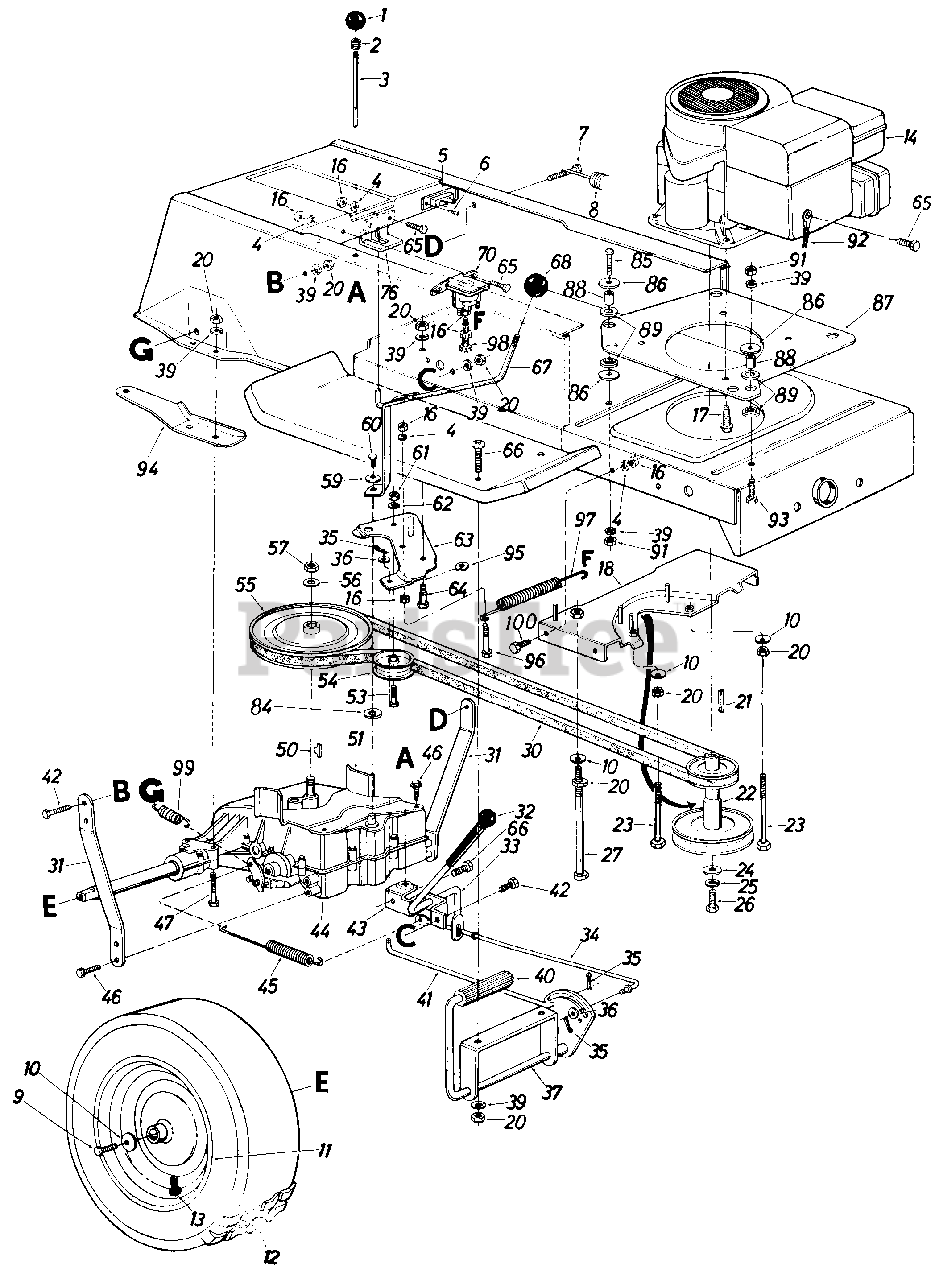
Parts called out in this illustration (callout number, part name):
1	Ball Knob 1.25" O.D. x 1/4-20 Thd.
2	Compression Spring .30" O.D. x 1.00" Lg.
3	Brake Lockout Rod
4	L-Wash. 1/4" I.D.
5	Circuit Breaker
6	Truss Hd. Phil. Scr. #10 x 1/2" Lg.
7	Hex Bolt 5/16-18 x 1.25" Lg.
8	Ext. Spring .99" O.D. x 11.00" Lg.
9	Hex Bolt 5/16-24 x .75" Lg.
10	Bell-Wash. 5/16" I.D.
11	Rear Wheel Rim Only
16	Hex Nut 1/4-20 Thd.
17	Hex Bolt 3/8-16 x 1.25" Lg.
18	Belt Guard Brk't. Ass'y.
20	Hex Nut 5/16-18 Thd.
21	Sq. Key 1/4" x 1/4" x 2.00" Lg.
22	Two Step Engine Pu I ley
23	Hex Bolt 5/16-18 x 5.25" Lg.
24	Fl-Wash. 7/16" I.D. x 1.25" O.D. x .180
25	L-Wash. 7/16" I.D.
26	Hex Bolt 7/16-20 x 1.50" Lg.
27	Hex Bolt 5/16-18 x 5.25" Lg.*
30	"V "-Belt "A" G lass 85" Lg. Bare Back
31	Transaxle Brace
32	Grip
33	Hill Holder Brake Handle
34	Brake Rod
35	Cotter Pin 3132" Dia. x 1 .00"
36	Fl-Wash. .344" I.D. x .625" O.D.
37	Brake and Clutch Pedal Ass'y.
39	L-Wash. 5/16" I.D.
40	Foot Pedal Pad
41	Clutch Rod
42	Hex Bolt 5/16-18 x .75" Lg.
43	Brake Lock and Handle Support Brk't.
44	Transaxle Complete
45	Ext. Spring .590" O.D. x 7.08" Lg.
46	Hex Wash. Hd. AB-Tap Scr. 5/16 x .62" Lg.
47	Hex Bolt 5/16-18 x 2.50" Lg.
50	#4 Hi-Pro Key 3/32 x 5/8" Dia.
51	Transaxle Belt Keeper
53	Hex Bolt 3/8-16 x 1.50" Lg.*
54	Flat Idler Pulley 3/8 I.D. x 2.75 O.D.
55	Transaxle Pulley
56	L-Wash. 1/2" I.D.
57	Hex Nut 1/2-20 Thd.*
59	Bell-Wash. .26" I.D. x .75" O.D.
60	Hex Bolt 1/4-28 x .62" Lg.
61	Hex Nut 3/8-16 Thd.
62	L-Wash. 3/8" I.D.
63	Idler Brk't. Ass'y
64	Shld. Scr. .437" Dia. x 1.80" Lg. (5/16-18)
65	Hex Bolt 1/4-20 x .62" Lg.
66	Truss Hd. Mach. 5/16-18 x .75" Lg.
67	Shift Lever Ass'y
68	Ball Knob 1.25" O.D. x 3/8 16 Thd.
70	Solenoid
76	Shift Lever Pivot Brk't.
84	Special Wash. 1.00" O.D.
85	Hex Bolt 5/16-24 x 1.25" Lg.
86	Fl-Wash. 1.25" O.D. x .320" I.D.
87	Engine Mounting Plate
88	Spacer
89	Engine Mounting Grommet
91	Hex Nut 5/16-24 Thd.
92	Electric Ground Wire
93	Hex Bolt 5/16-24 x 1.50" Lg.*
94	Transaxle Support Brk't. R.H.
95	Wave Wash.
96	Hex Bolt 1/4-20 x 2.50" Lg.
97	Ext. Spring
98	Hex Bolt 1/4-20 x 2.50" Lg.
99	Brake Return Spring
100	Hex Bolt 1/4-28 x .75" Lg. Grade 5
